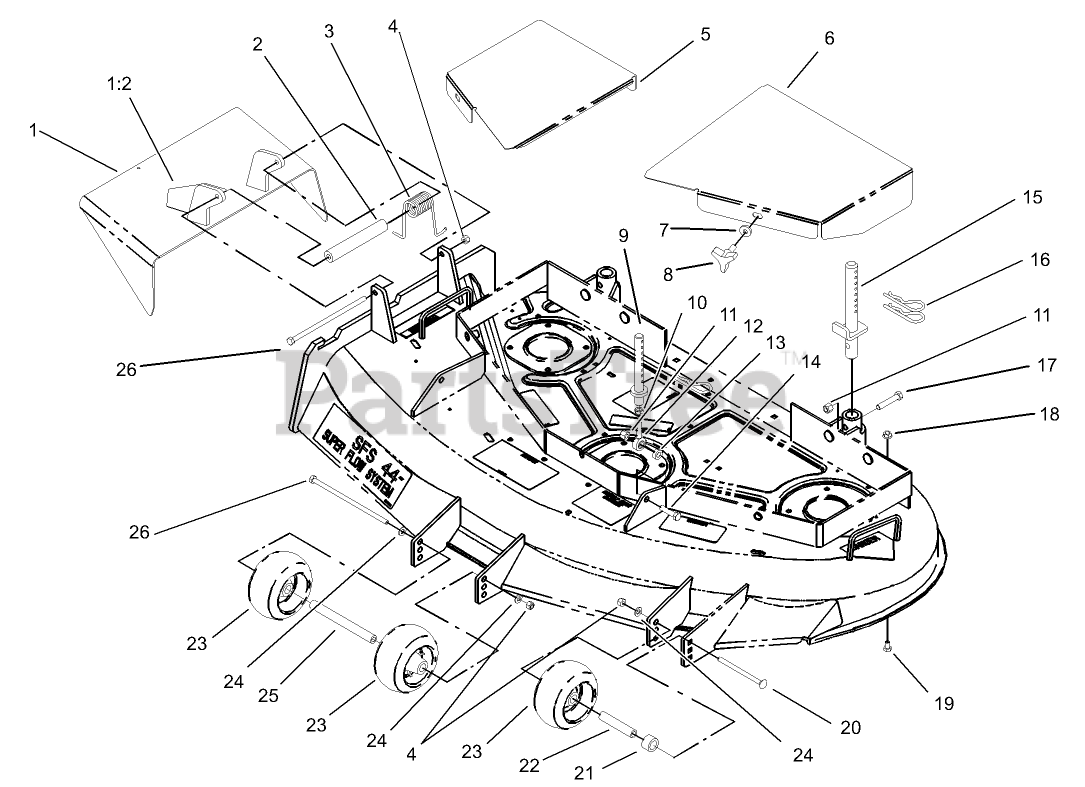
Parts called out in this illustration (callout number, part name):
1	Deflector ASM
1:2	DECAL-DANGER
2	SPACER
3	SPRING-TORSION
4	NUT-LOCK, NI
5	COVER-BELT, RH
6	COVER-BELT, LH
7	WASHER-RUBBER
9	FRONT PIN ASM
10	NUT-HJ
11	NUT-LOCK, NI
12	BALLJOINT
13	SPACER
14	SCREW-HH
15	REAR PIN ASM
16	PIN-HAIR
17	SCREW-HH
18	NUT-HF
19	SCREW-HH
20	SCREW-CARR
21	SPACER-WHEEL
22	BUSHING-ROLLER
23	WHEEL-GAGE
24	WASHER-PLAIN
25	SPACER-WHEEL
26	SCREW-HH
